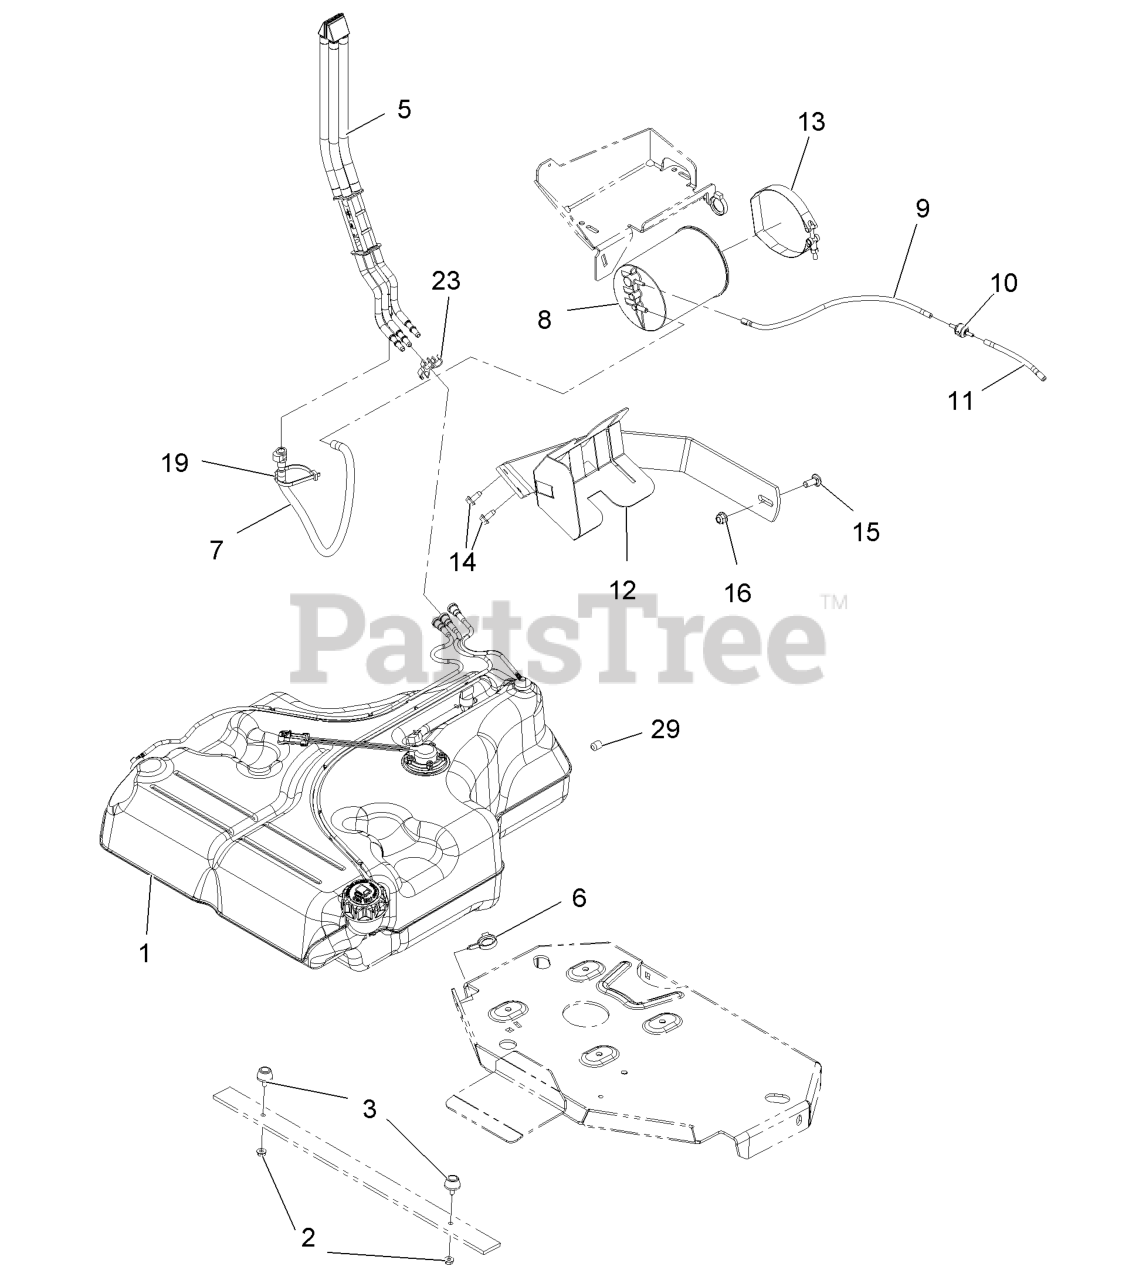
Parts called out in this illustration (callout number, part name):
3	BUMPER-RUBBER
5	FUEL MANIFOLD VENT ASM
6	CLAMP-HOSE
7	VENT HOSE ASM
8	CANISTER-CARBON, 1200CC
9	HOSE-VENT, FORMED
11	HOSE-VENT, FORMED
12	MOUNT-CANISTER
13	CLAMP, T-BOLT
14	Screw-HWH 5/16-18 X 3/4 Tf
15	SCREW-CARR
16	NUT-HF, NI
19	TIE-PLASTIC
23	CLIP-SPACER
29	PLUG-PORT
